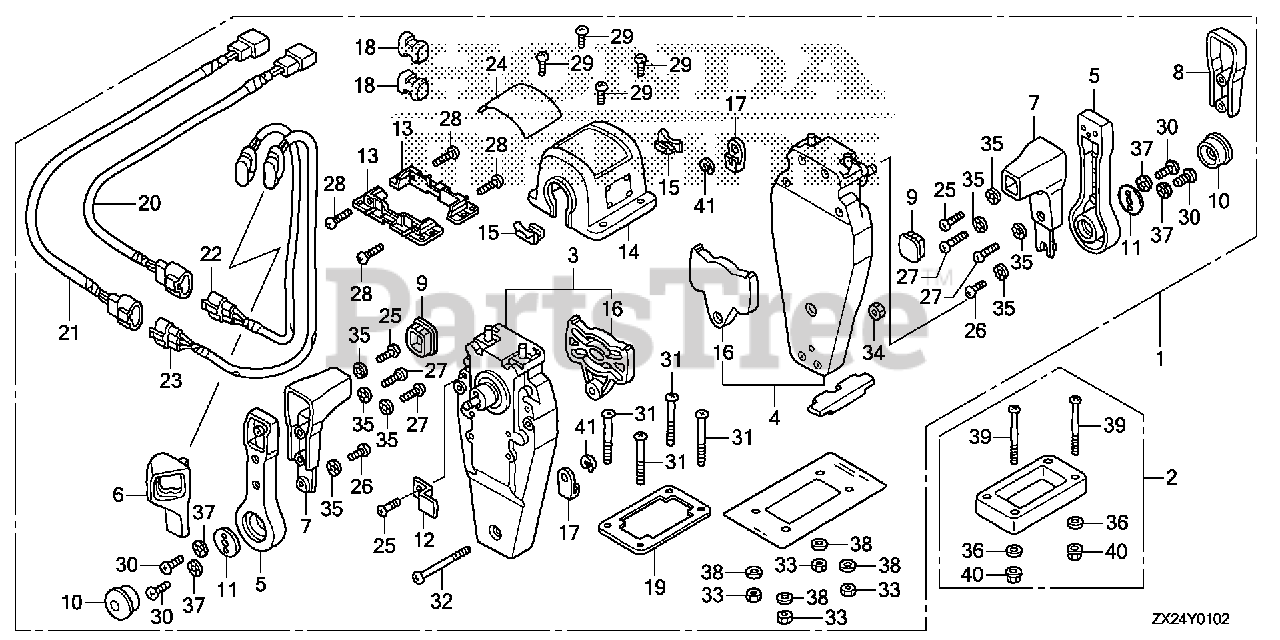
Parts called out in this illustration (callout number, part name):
1	BOX KIT, REMOTE CONTROL (TOP MOUNT DUAL)(R)
2	SPACER KIT, REMOTE CONTROL BOX (TOP MOUNT DUAL)
3	HOUSING ASSY., L. (INNER) (TOP MOUNT)
4	HOUSING ASSY., R. (INNER) (TOP MOUNT)
5	HANDLE, REMOTE CONTROL
6	COVER, L. GRIP
7	GRIP, REMOTE CONTROL HANDLE
8	COVER, DUAL GRIP
9	CAP, GRIP
10	BUTTON, THROTTLE
11	PLATE, HANDLE
12	PLATE, CABLE CLAMP
13	BRACKET, REMOTE CONTROL HOUSING
14	HOUSING, DUAL REMOTE CONTROL BOX
15	HOUSING, LEAD
16	PLATE, DWELL
17	TERMINAL, CABLE
18	SPACER, CABLE CLAMP
19	GASKET, DUAL
20	SUB-HARNESS ASSY., POWER TRIM-TILT (A)
21	SUB-HARNESS ASSY., POWER TRIM-TILT (B)
22	SWITCH ASSY., POWER TRIM-TILT (A)
23	SWITCH ASSY., POWER TRIM-TILT (B)
24	MARK, REMOTE CONTROL (DUAL)
25	SCREW, PAN (5X16)
26	SCREW, PAN (5X10)
27	SCREW, PAN (5X20)
28	SCREW, PAN (5X18)
29	SCREW, PAN (4X10)
30	SCREW, PAN (6X18)
31	SCREW, PAN (5X40)
32	SCREW, PAN (5X55)
33	NUT, HEX. (5MM)
34	NUT, HEX. (5MM)
35	WASHER, LOCK (5MM)
36	WASHER, PLAIN (5MM)
37	WASHER, LOCK (6MM)
38	WASHER, PLAIN (5MM)
39	SCREW, PAN (5X65)
40	NUT, HEX. (5MM)
41	E-RING (6MM)
